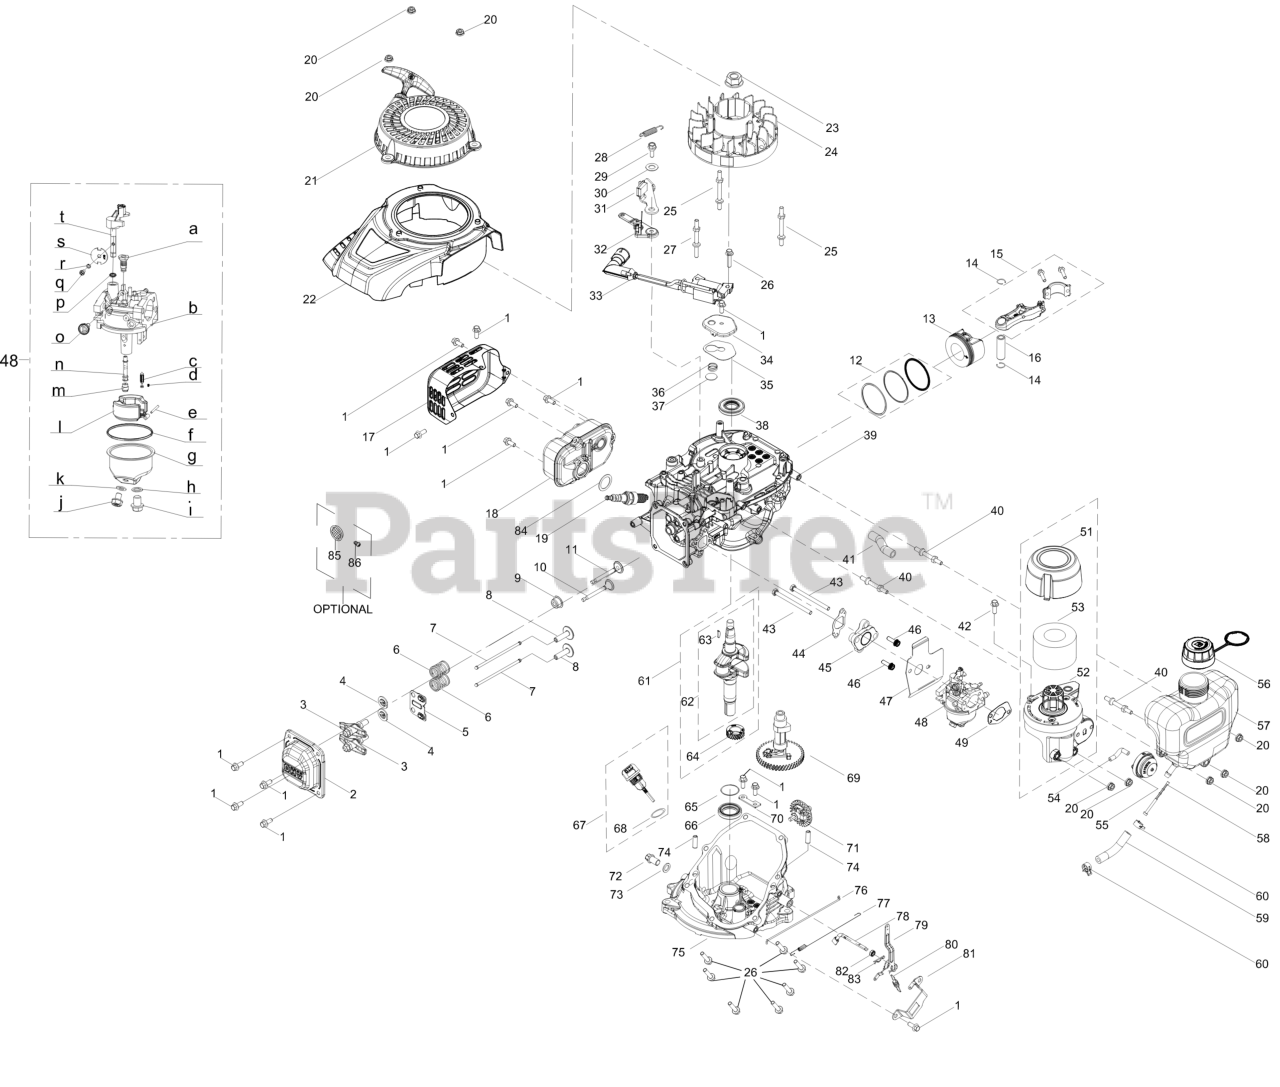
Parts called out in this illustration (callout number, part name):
1	BOLT M6-1 x 14 GR8.8
2	VALVE COVER
4	VALVE RETURN SPRING
5	PUSH ROD GUIDE
6	VALVE SPRING
9	INTAKE VALVE SEAL
10	EXHAUST VALVE
11	INTAKE VALVE
12	PISTON RING SET
14	WRIST PIN CLIP
15	CONNECTING ROD ASSEMBLY
17	MUFFLER GUARD
18	MUFFLER
19	SPARK PLUG (F5RTC/RN11YC4/BPR5ES)
21	STARTER RECOIL ASSEMBLY
22	SHROUD ASSEMBLY
23	FLYWHEEL NUT M14-1.5
24	FLYWHEEL
25	STUD M6 x 75
26	BOLT M6-1 x 25 GR8.8
27	STUD M6 x 73
28	ENGINE BRAKE SPRING
29	ENGINE BRAKE PIN M6-1.0 MM
30	FLAT WASHER 10x20x1.0 MM
31	ENGINE BRAKE ARM
32	ENGINE BRAKE LOWER BRACKET
33	IGNITION COIL
34	BREATHER COVER PLATE
35	BREATHER GASKET
36	BREATHER VALVE SPRING
37	BREATHER VALVE
40	FUEL TANK MOUNTING STUD M6X59.5
41	BREATHER HOSE
42	BOLT M6 x 16
43	BOLT M6X80
44	CARBURETOR INSULATION GASKET
45	CARBURETOR INSULATOR
46	BOLT M6X20
47	CARBURETOR GASKET
48	CARBURETOR
49	AIR FILTER BASE GASKET
51	AIR FILTER COVER
52	AIR FILTER BASE
53	AIR FILTER - FOAM
54	PRIMER HOSE
55	VENTED PRIMER ASSEMBLY
56	FUEL CAP W/TETHER
57	Fuel Tank Assembly
58	FUEL FILTER
59	FUEL HOSE
60	CARBURETOR HOSE CLAMP
61	CRANKSHAFT ASSEMBLY
62	CRANKSHAFT ASSEMBLY
63	WOODRUFF KEY
65	THRUST WASHER
66	LOWER CRANKSHAFT SEAL
67	DIPSTICK ASSEMBLY
68	DIPSTICK SEAL
69	CAMSHAFT ASSEMBLY
70	GOVERNOR GEAR MOUNTING PLATE
71	GEAR GOVERNOR
72	OIL DRAIN PLUG
73	FLAT WASHER
74	DOWEL PIN 7X20
75	CRANKCASE COVER
76	THROTTLE LINKAGE
77	THROTTLE LINKAGE SPRING
78	GOVERNOR ARM SHAFT
79	GOVERNOR ARM ASSEMBLY
80	GOVERNOR SPRING
81	COMPONENT BRACKET
82	GOVERNOR SEAL
84	MUFFLER GASKET
85	SPARK ARRESTOR
86	SPARK ARRESTOR SCREW
